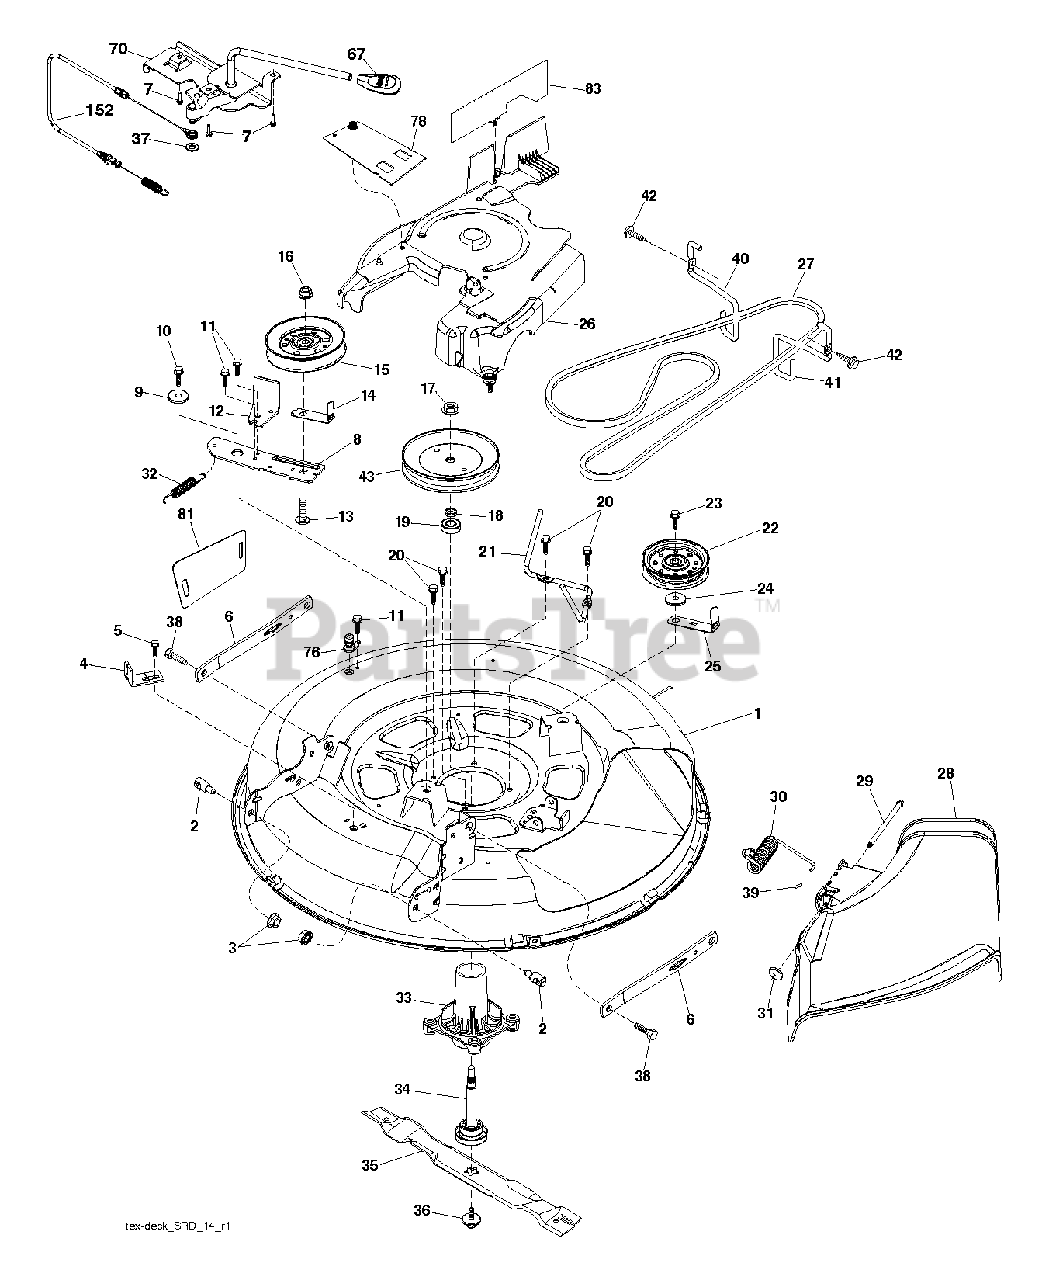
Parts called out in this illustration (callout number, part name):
1	DECK.WELDMENT.PNT.30"SRD
2	STUD.FASTNER.W/ANTI-ROTATE
3	NUT LOCK HEX FLANGE 5/16-18
4	BRACKET.CLUTCH.CABLE
5	BOLT.5/16HEX.WHS.HD
6	ARMS.SUSP.MOWER.REAR.SRD
7	SCREW.#10 X 0.750.BOS
8	ARM.IDLER.30"SRD
9	SPACER.RETAINER
10	SCREW 3/8-16X1
11	SCREW.1/4-20X5/8
12	RP ARM.BRAKE.MOWER.38"LH.TEX
13	BOLT.3/8-16X1.50
14	KEEPER, BELT IDLER
15	PULLEY.IDLER.4.25
16	NUT LOCK FLG 3/8-16 UNC
17	NUT.FLANGE.LOCK.TOP
18	WASHER.SPACER.MANDREL
20	SCREW, WASHER HEAD
21	KEEPER.BELT.MANDREL.30"
22	PULLEY.IDLER.FLAT.46.PR.DR.
23	SCREW LT
24	WASHER
25	KEEPER.BELT.30"SRD
26	COVER.ASM.MANDREL.30"
27	V-BELT.DRIVE.MOWER.30"
28	SHIELD.DEFLECT.MWR.30S.BLACK
29	PIN.HINGE.30".SRD
30	SPRING.TORSION.DEFLECT
31	NUT PUSH M
32	SPRING RETURN
33	HOUSING.MANDREL.4PT.
34	SHAFT.ASM.MDRL.N/GREASE.38
35	BLADE, MULCH.LRV30
36	BOLT.WASHER.ASM.7/16-2
37	WASHER
38	BOLT.SHOULDER
39	CAP-SLEEVE LT
40	KEEPER.BELT.ENGINE.LH.LT.SRD
41	KEEPER.BELT.ENGINE.RH.LT.SRD
42	SCREW, 3/8-16X3/4
43	PULLEY, MANDREL 6.5 PD
67	HANDLE.CLUTCH.CABLE.LT
70	CLUTCH.ASM.MANUAL.LT.PRED
76	PORT.WASHOUT
78	GUARD ARM CLUTCH
81	SHIELD SUSPENSION
83	GUARD LEFT
152	CABLE.CLUTCH.MANUAL.
